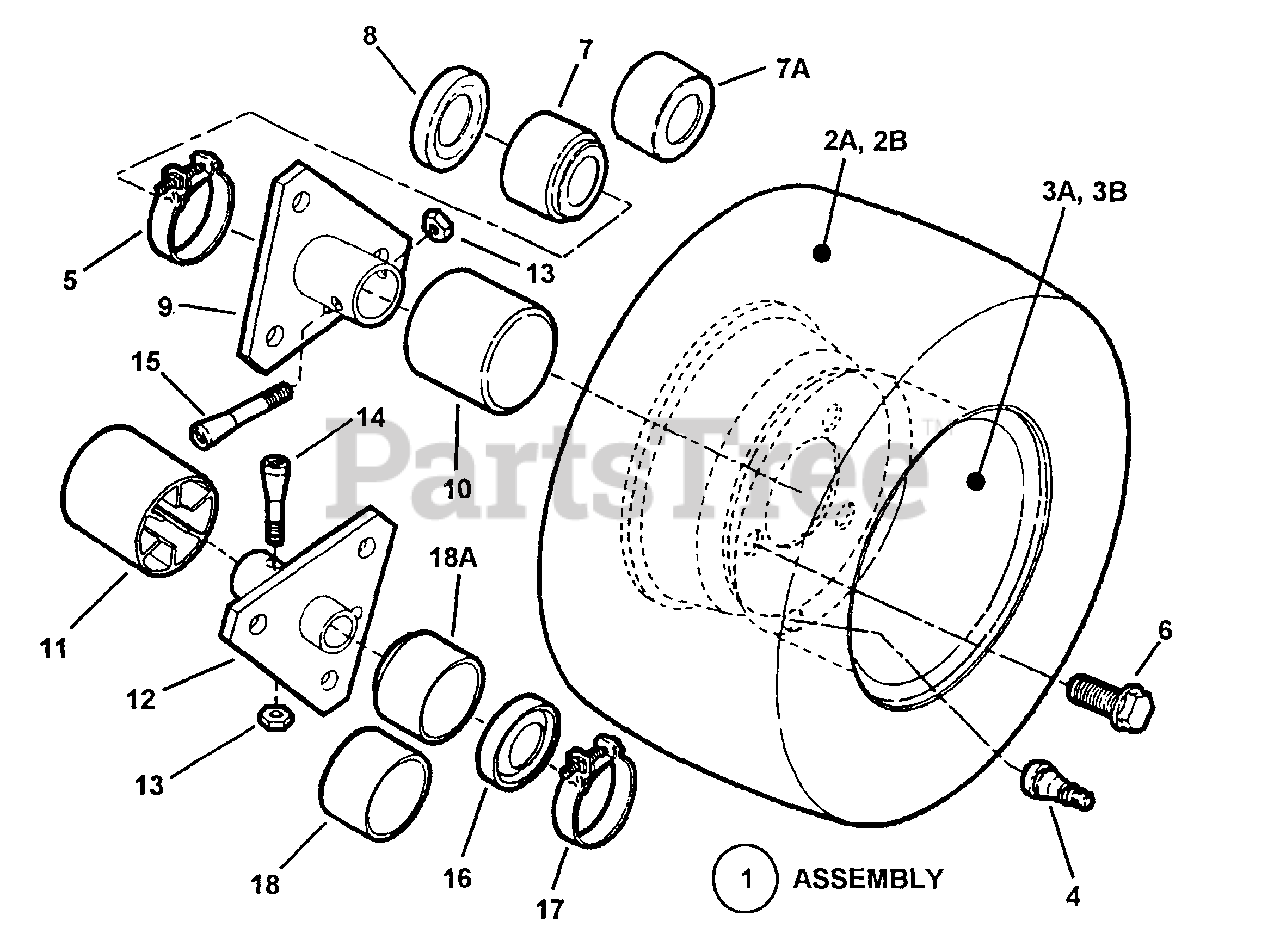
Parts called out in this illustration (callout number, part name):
1	ASSEMBLY, Rear Tire & Rim (NLA use 7058951)
1	ASSEMBLY, Rear Tire & Rim
2A	TIRE, Wide, 16-6.50 x 8, Carlisle
2B	TIRE, 16-6.50 x 8 Kenda
3A	RIM, (8 x 5.375)
3B	RIM, Extra Wide,
4	VALVE, Air (Snap-in)
5	CLAMP, Boot, 2"
5	CLAMP, Right Hand (3.0" ID)
6	BOLT, 1/2-20 x 3/4" Lug
7	CAP, Seal .93" ID x 2.625" OD
7A	CAP, Seal 1.0" ID x 1.67" OD
8	SEAL, Oil 1.22" ID x 1.875" OD (Right Hand)
9	HUB, Wheel RH, 3 Hole 1" ID
10	CAP, Hub (Right Hand)
11	CAP, Hub (Left Hand)
12	HUB, Wheel LH, 3 Hole 3/4" ID
13	NUT, 5/16-24 Hex Center Lock
14	BOLT, 5/16-24 x 1-5/8" Tapered (Left Hand)
15	BOLT, 5/16-24 x 2" Tapered (Right Hand)
16	SEAL, OIL .750" ID x 1.832" OD (Left Hand)
17	CLAMP, Boot, 2"
18	CAP, Seal 3/4" (Left Hand)
18A	CAP, Seal .750" ID x 1.875" OD (Left Hand)
